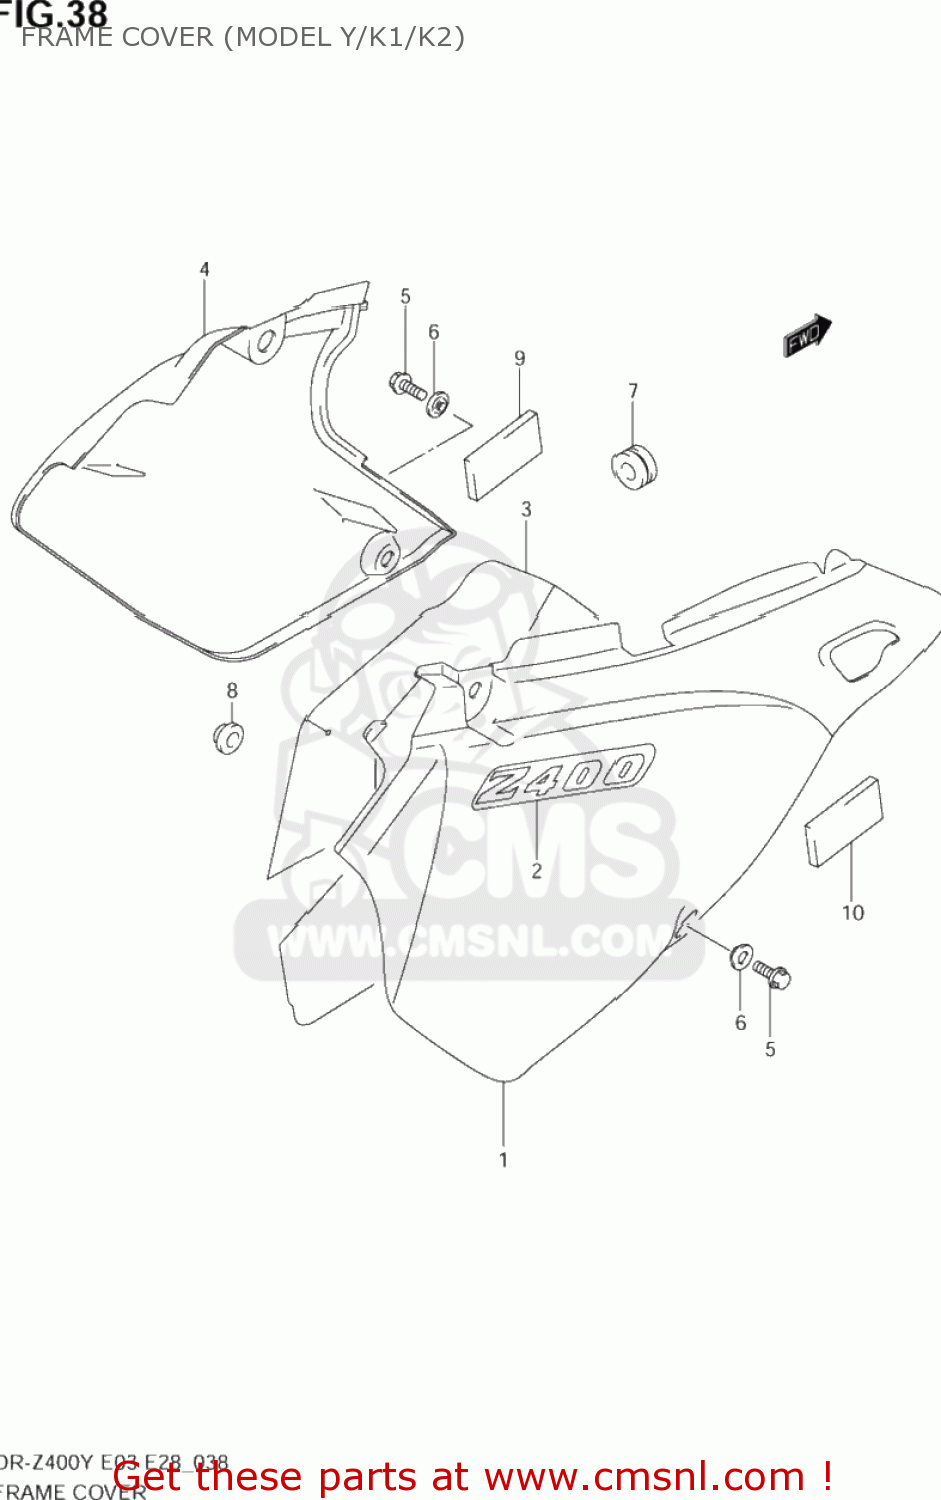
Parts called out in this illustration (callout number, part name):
1	COVER,FRAME,RIGHT
2	EMBLEM,FRAME COVER
3	SHIELD,FRAME COVER,R
4	COVER,FRAME,L(YELLOW)
5	BOLT
6	WASHER
7	CUSHION
8	CUSHION
9	CUSHION,FRAME COVER,L
10	CUSHION
